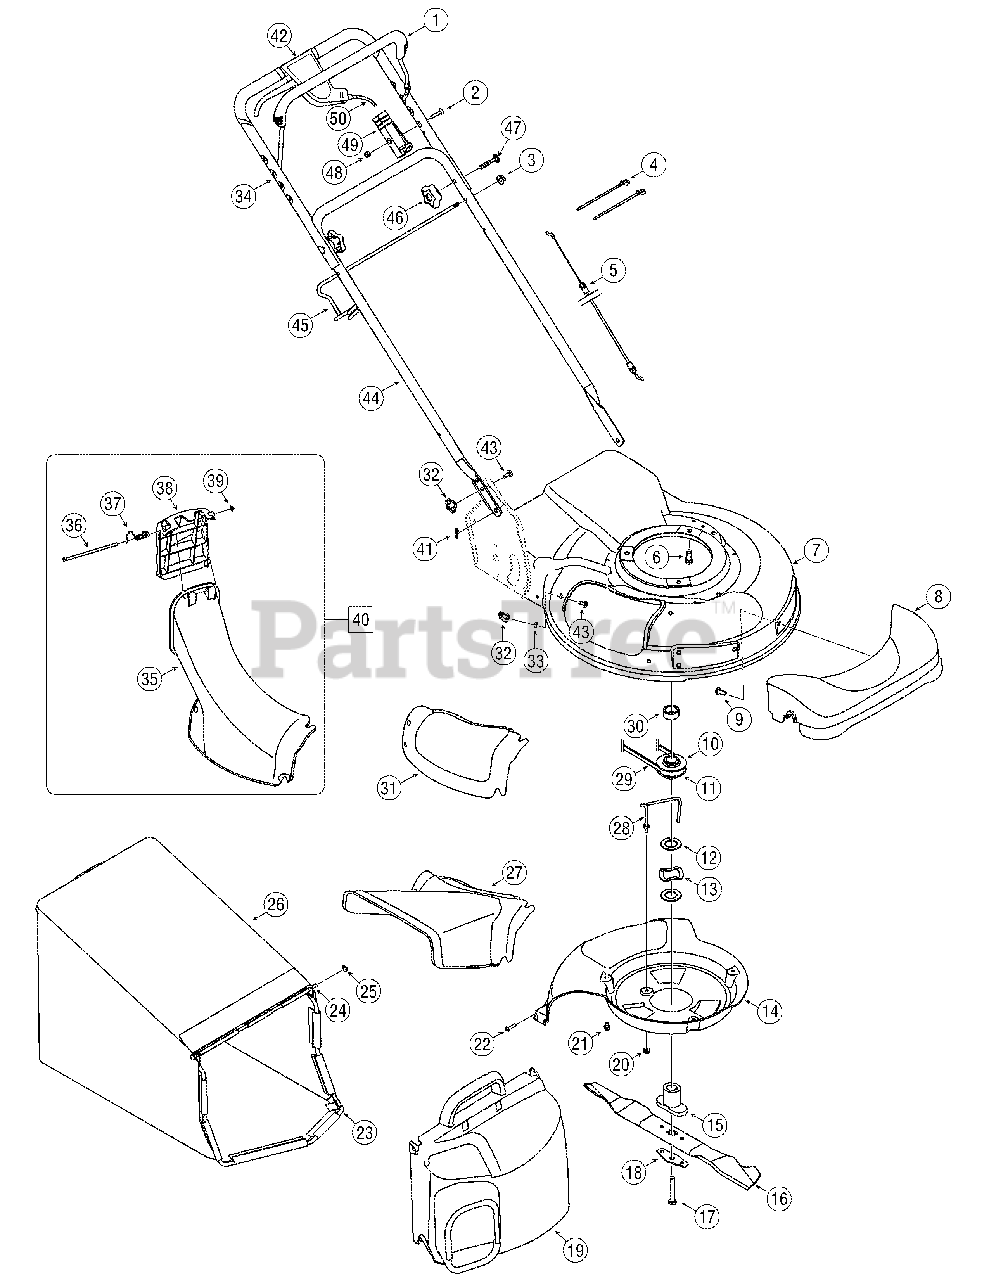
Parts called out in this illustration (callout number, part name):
1	Lever Assembly
2	Machine Screw, 1/4-20 x 1.310
3	Flange Lock Nut, 5/16-18
4	Cable Tie
5	Control Cable, 47-inch
6	TT Screw, 3/8-16 x 1.00
9	HL Screw, 5/16-14 x .750
10	Upper Half Pulley
11	Key Half Pulley
12	Flat Wash., 1.031 x 1.620 x .095
13	Wave Wash., 1.5 x 1.0 x .029
14	Rear Baffle
15	Blade Adapter
16	21-inch Mulching Blade
17	HH Cap Screw, 3/8-24 x 2.50
18	Bell Blade Spacer
19	Grass Bag Cover Assembly
20	Flange Lock Nut 1/4-20
21	TT Screw 1/4-20 x .375
22	HL Screw 1/4-15 x .75
24	Grass Bag Pivot Rod
25	Cap Speed Nut
26	Grass Bag Assembly
27	Side Discharge Chute
28	Belt Keeper Rod
29	V-Belt
30	Sleeve Spacer
31	Mulch Cover
32	Wing Nut
35	Top Discharge Chute
36	Chute Door Pivot Rod
37	Torsion Spring
38	Top Discharge Door Chute
40	Top Discharge Chute Assembly
41	Cotter Pin
42	Drive Control Assembly
43	Carriage Screw 1/4-20 x .75
46	Star Knob
47	Carriage Bolt 5/16-18 x 2
48	Hex Lock Nut 1/4-20
49	ERS Housing
50	51-inch Cable
